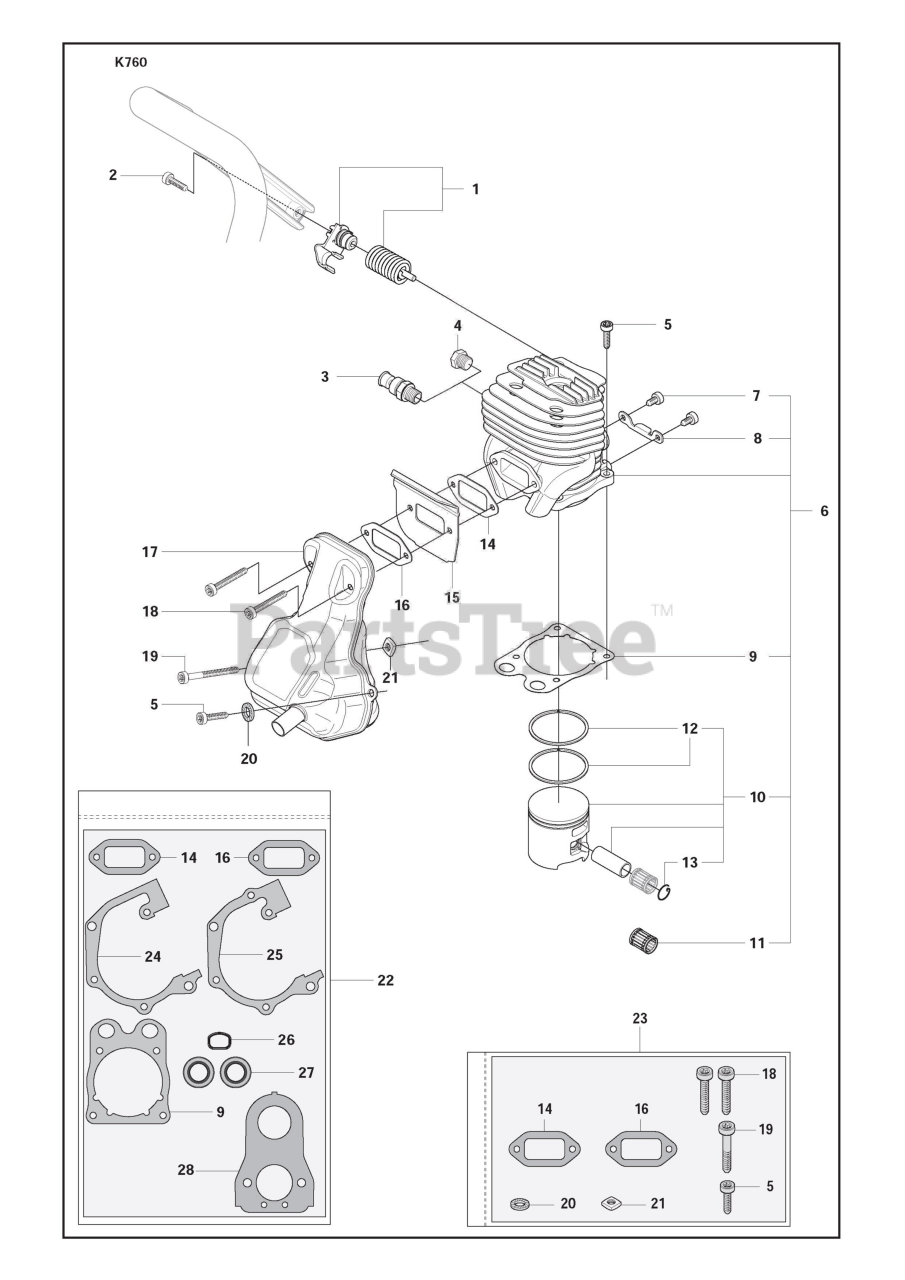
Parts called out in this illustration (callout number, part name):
1	Vib.Insulator
3	Decompression Valve
6	Cylinder Assy
9	Cylinder Base Gasket
10	Piston Assy
11	Needle Bearing
12	Piston Ring
15	Cooling Plate
16	Gasket Muffler
17	Muffler
22	Gasket Kit
23	Muffler Mounting Kit
24	Gasket Crankcase
25	Gasket Crankcase
27	Sealing Ring
28	Gasket Carburettor
